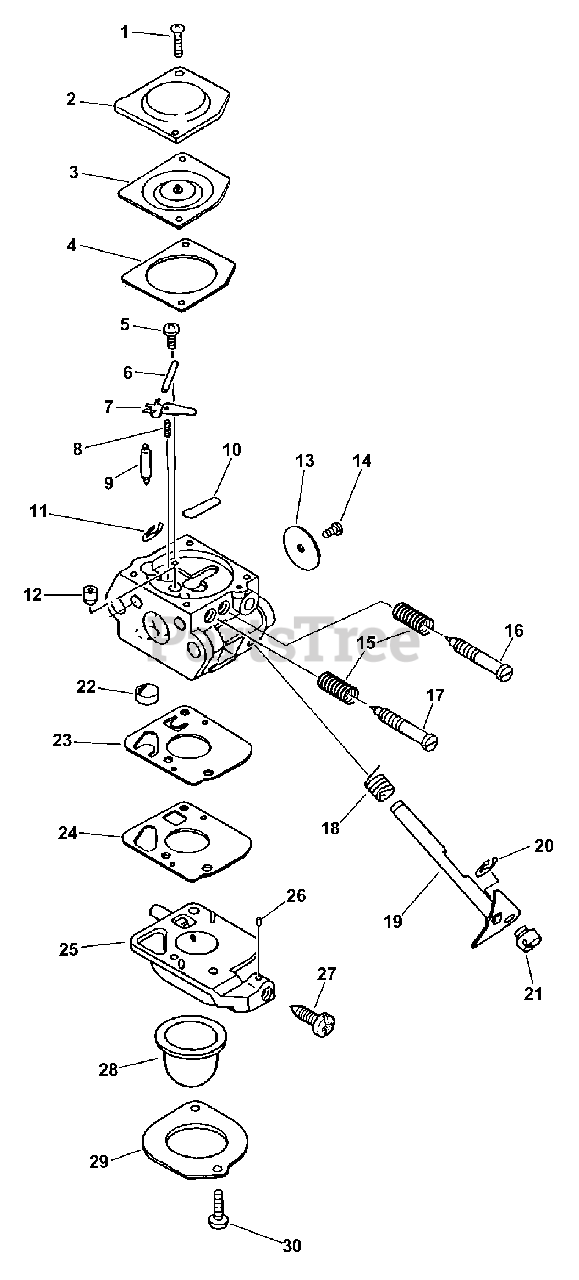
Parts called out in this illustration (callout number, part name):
1	SCREW
2	COVER, METERING DIAPHRAGM
3	DIAPHRAGM
4	GASKET, DIAPHRAGM
5	SCREW
6	PIN, METERING LEVER
7	LEVER, METERING
8	SPRING
9	VALVE, NEEDLE
10	PLUG, WELCH
11	E-RING
12	NOZZLE, CHECK VALVE
13	VALVE, THROTTLE
14	SCREW
15	SPRING, NEEDLE
16	NEEDLE, HIGH SPEED
17	NEEDLE, LOW SPEED
18	SPRING, THROTTLE RETURN
19	SHAFT, THROTTLE
20	CLIP
21	SWIVEL
22	STRAINER
23	DIAPHRAGM, PUMP
24	GASKET, PUMP
25	BODY ASSY, PURGE
26	PIECE, FRICTION
27	SCREW, IDLE ADJUST
28	BULB, PURGE
29	RETAINER
30	SCREW
